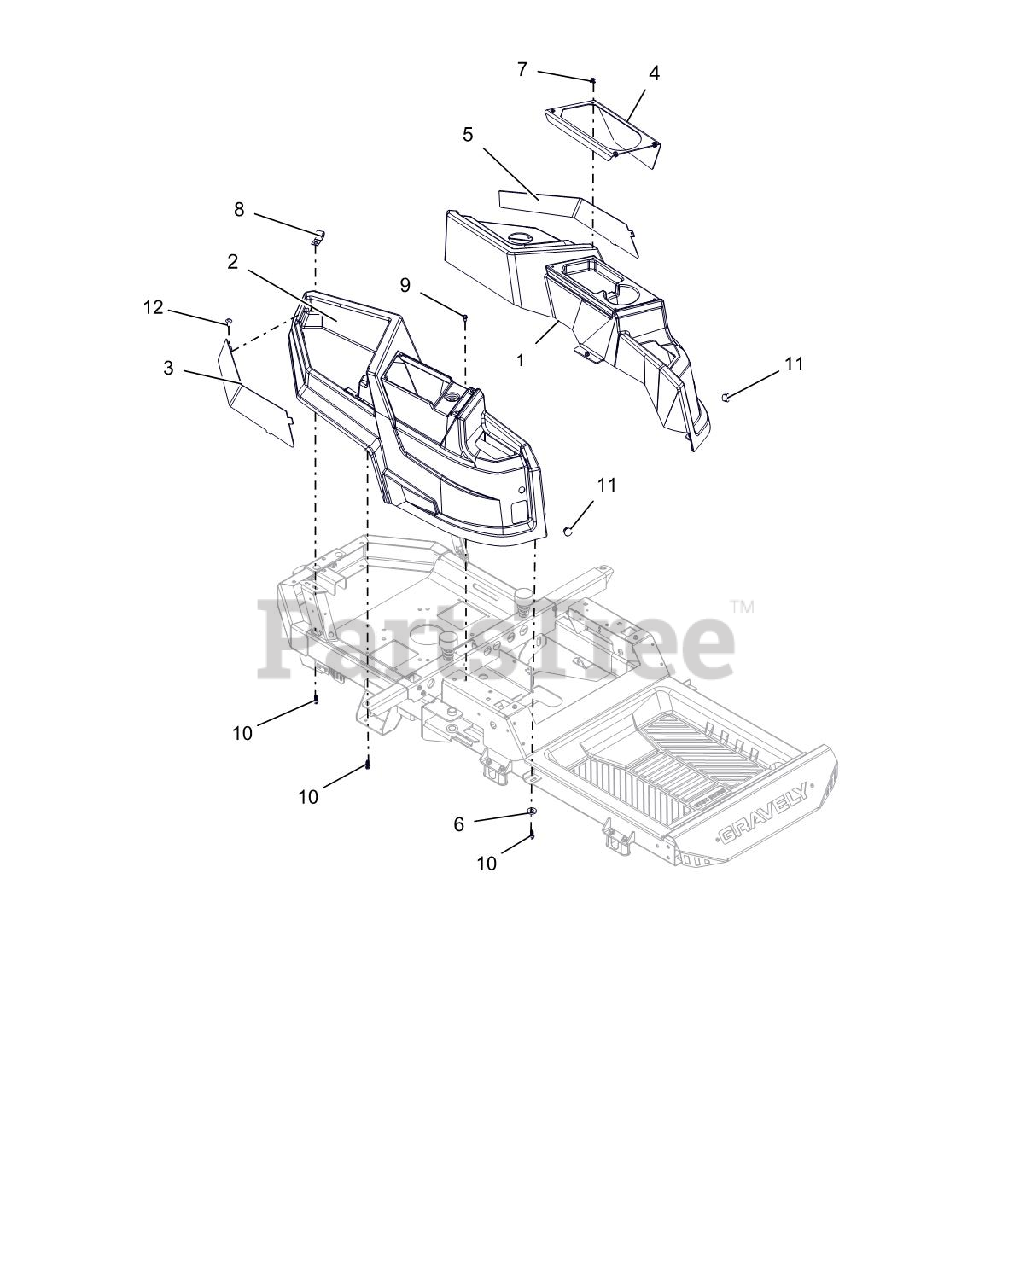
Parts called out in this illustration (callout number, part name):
1	FENDER, LH -ZOOM
2	FENDER, RH -ZOOM
3	WLMT, FENDER BLOCKOFF-RH
4	PANEL, CUPHOLDER/STORAGE (LH)
5	WLMT, FENDER BLOCKOFF-LH
6	WSHR-FL-STL .406X1.00X.188 YWZ
7	RIVET, PLASTIC .195 DIA.
9	SCR-TAP .25-20X.50 HWH TR YWZ
10	SCR-.312X.75 #14H H/W/H H/L CZ
11	PLUG, HOLE .75 (BLACK)
12	XMAS TREE FASTNER-BLACK
